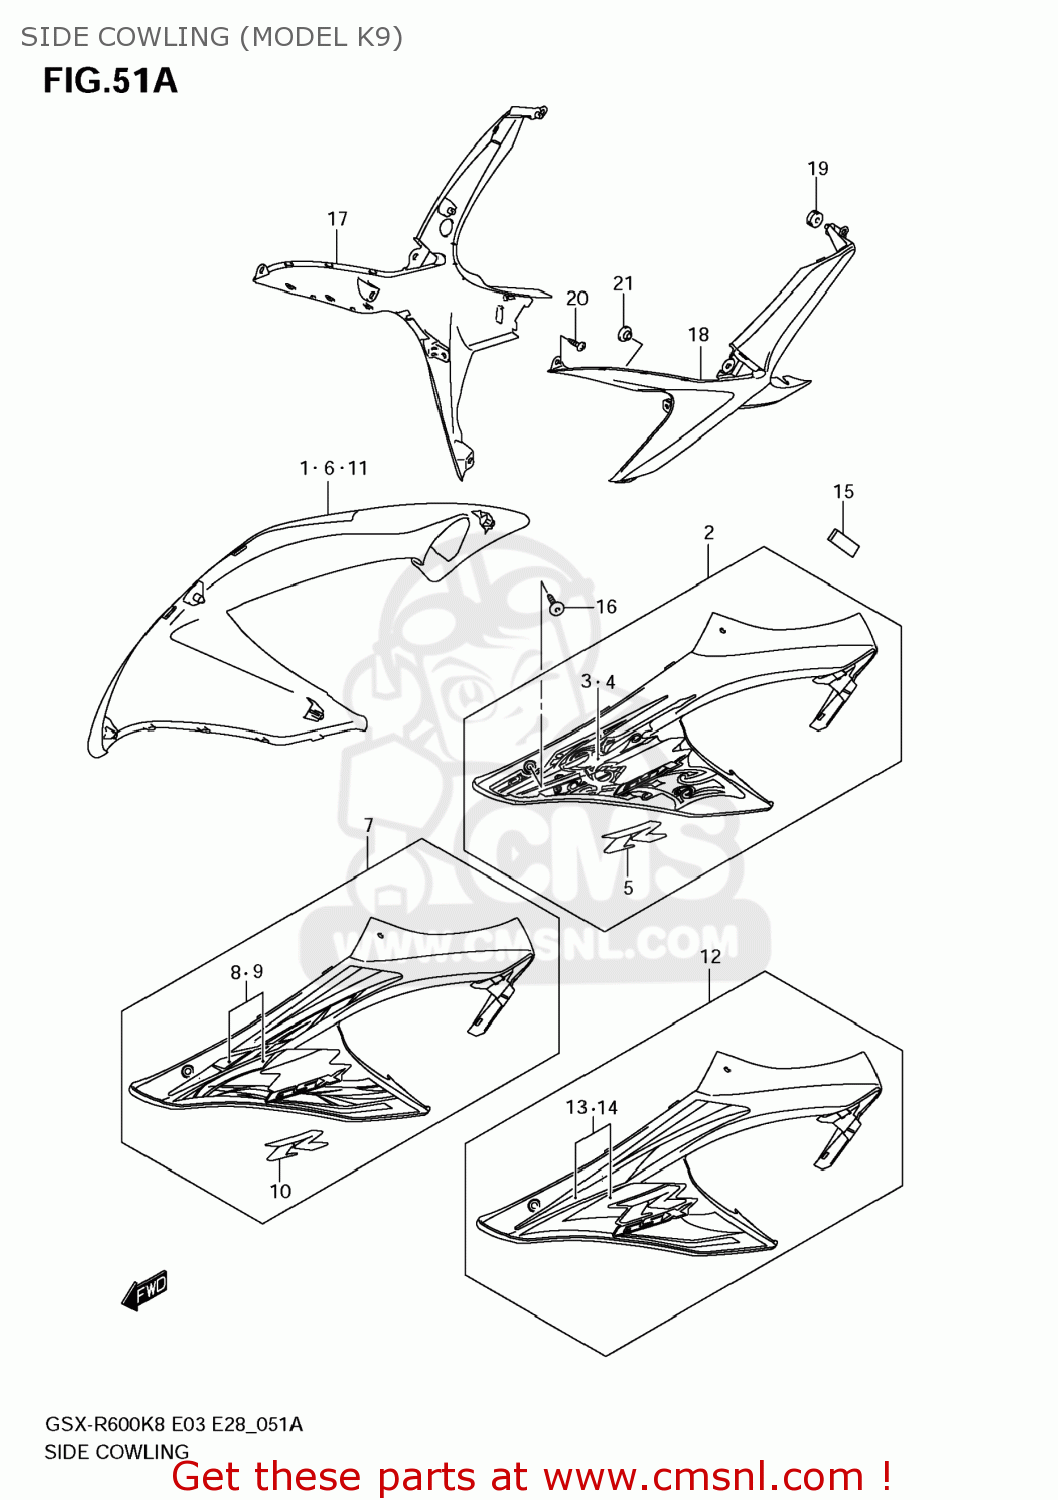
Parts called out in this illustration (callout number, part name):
1	COWLING,SIDE,R(BLACK)
2	COWLING,SIDE,L(BLACK)
3	TAPE,COWL SIDE,R
4	TAPE,COWL SIDE,L
5	EMBLEM,R
6	COWLING,SIDE,R(ORANGE)
7	COWLING,SIDE,L(ORANGE)
8	TAPE SET,COWL SIDE,R
9	TAPE SET,COWL SIDE,L
10	EMBLEM,R
11	COWLING,SIDE,R(WHITE)
12	COWLING,SIDE,L(WHITE)
13	TAPE SET,COWL SIDE,R
14	TAPE SET,COWL SIDE,L
15	CUSHION,SIDE COWL
16	SCREW(5X16)
17	COVER,UNDER COWL,R
18	COVER,UNDER COWL,L
19	CUSHION
20	SCREW
21	CUSHION
